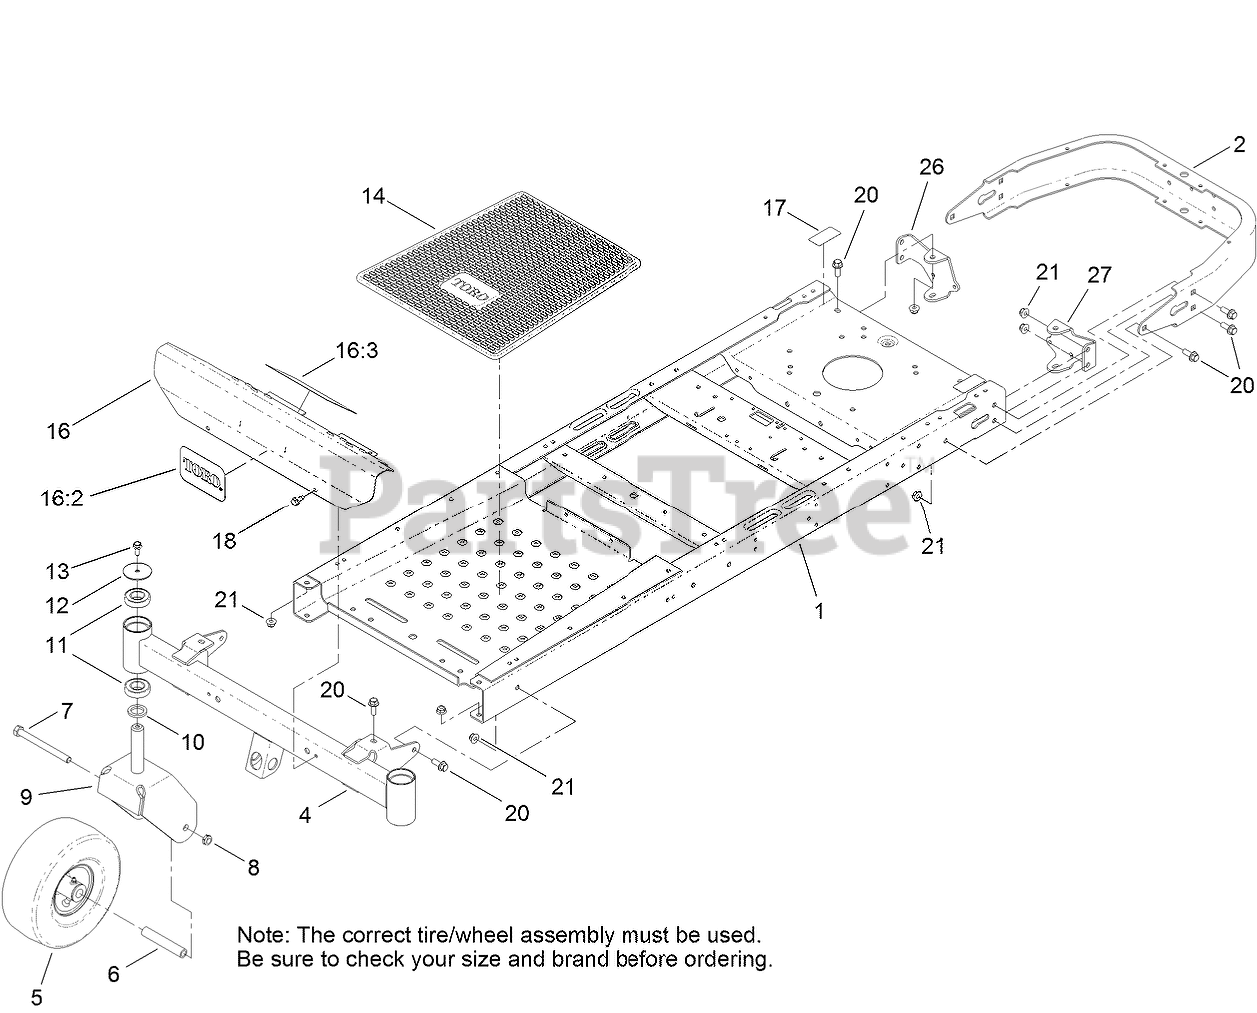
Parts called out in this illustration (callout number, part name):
2	BUMPER-REAR
4	AXLE-FRONT
5	CASTER WHEEL ASM (CST)
5	CASTER WHEEL ASM (KENDA)
6	BUSHING-SPANNER
7	SCREW-HH
8	NUT-LOCK, NI
9	FORK-CASTER
10	WASHER-THRUST
11	BEARING-BALL
12	WASHER
13	SCREW-HHF
14	MAT-FLOOR
16	FOOTREST ASM
16:3	DECAL-DANGER
17	DECAL-BYPASS
18	SCREW-HWHTF
20	SCREW-HHF
21	NUT-HF, NI
26	MOUNT-HYDRO, REAR (RH)
27	MOUNT-HYDRO, REAR (LH)
